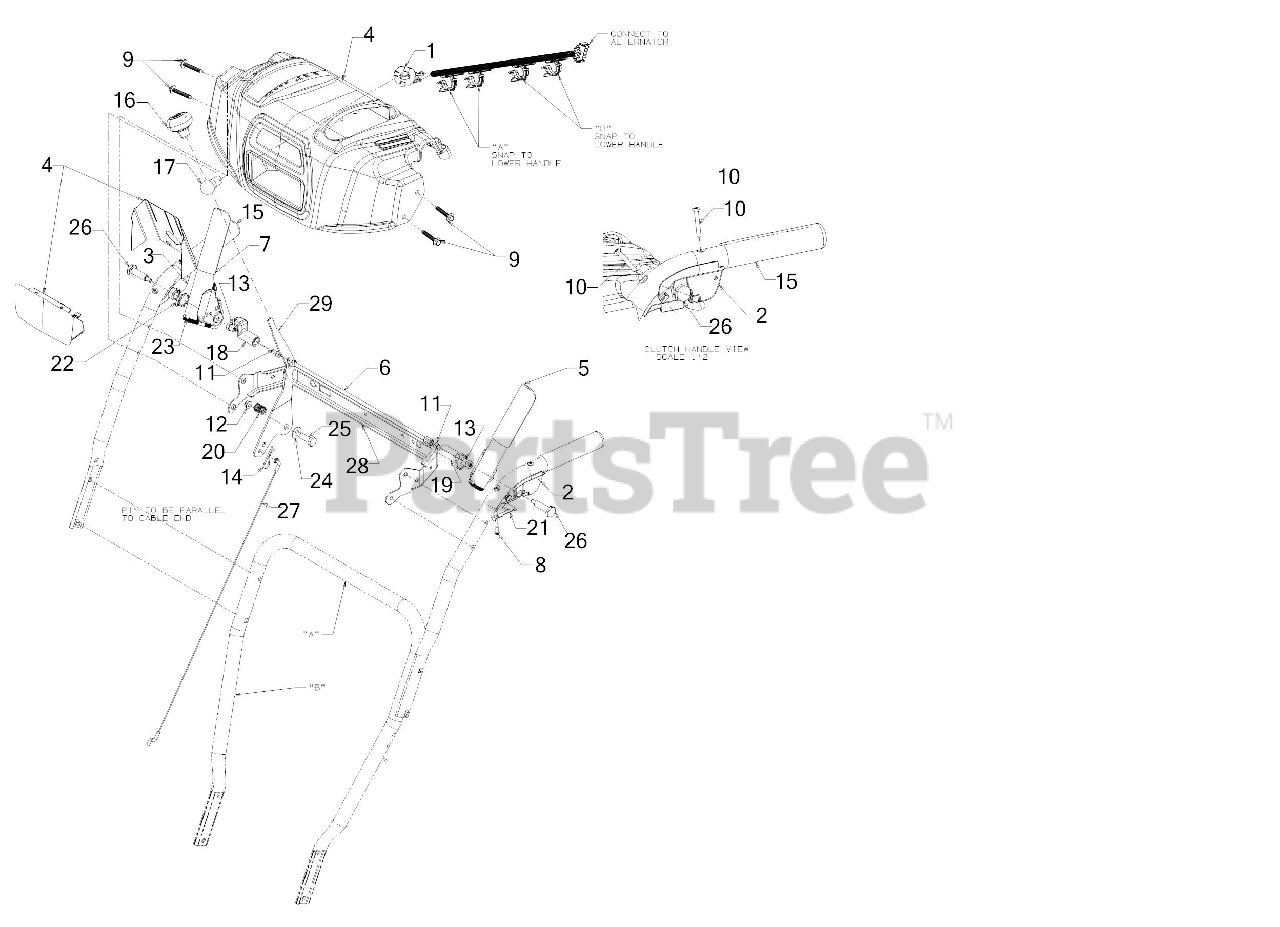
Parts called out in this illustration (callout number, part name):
1	HEADLIGHT HARNESS ASSEMBLY
2	CLUTCH LOCK HANDLE ASSEMBLY (LH)
3	CLUTCH LOCK HANDLE ASSEMBLY (RH)
4	HANDLE PANEL ASSEMBLY
5	HANDLE ASSEMBLY (LH)
7	ENGAGEMENT HANDLE ASSEMBLY (RH) (BLACK)
8	SCREW #8-16 x .50
9	SCREW 1/4-20 x 1.625
10	SCREW #10-24 x 1.375
11	SCREW 1/4-20 x .50
12	FLANGE LOCK NUT
13	HEX NUT W/PATCH
14	INTERNAL COTTER PIN
16	SHIFT KNOB
19	CLUTCH LOCK CAM
20	COMPRESSION SPRING
21	CLUTCH SPRING
22	TORSION SPRING
23	RUBBER BUMPER
24	FLAT WASHER
25	SHOULDER SCREW
26	SHOULDER SCREW .437 x 1.345 1/4-20
27	SPEED SELECTOR CABLE (PLASTIC)
28	HANDLE SUPPORT BRACKET
